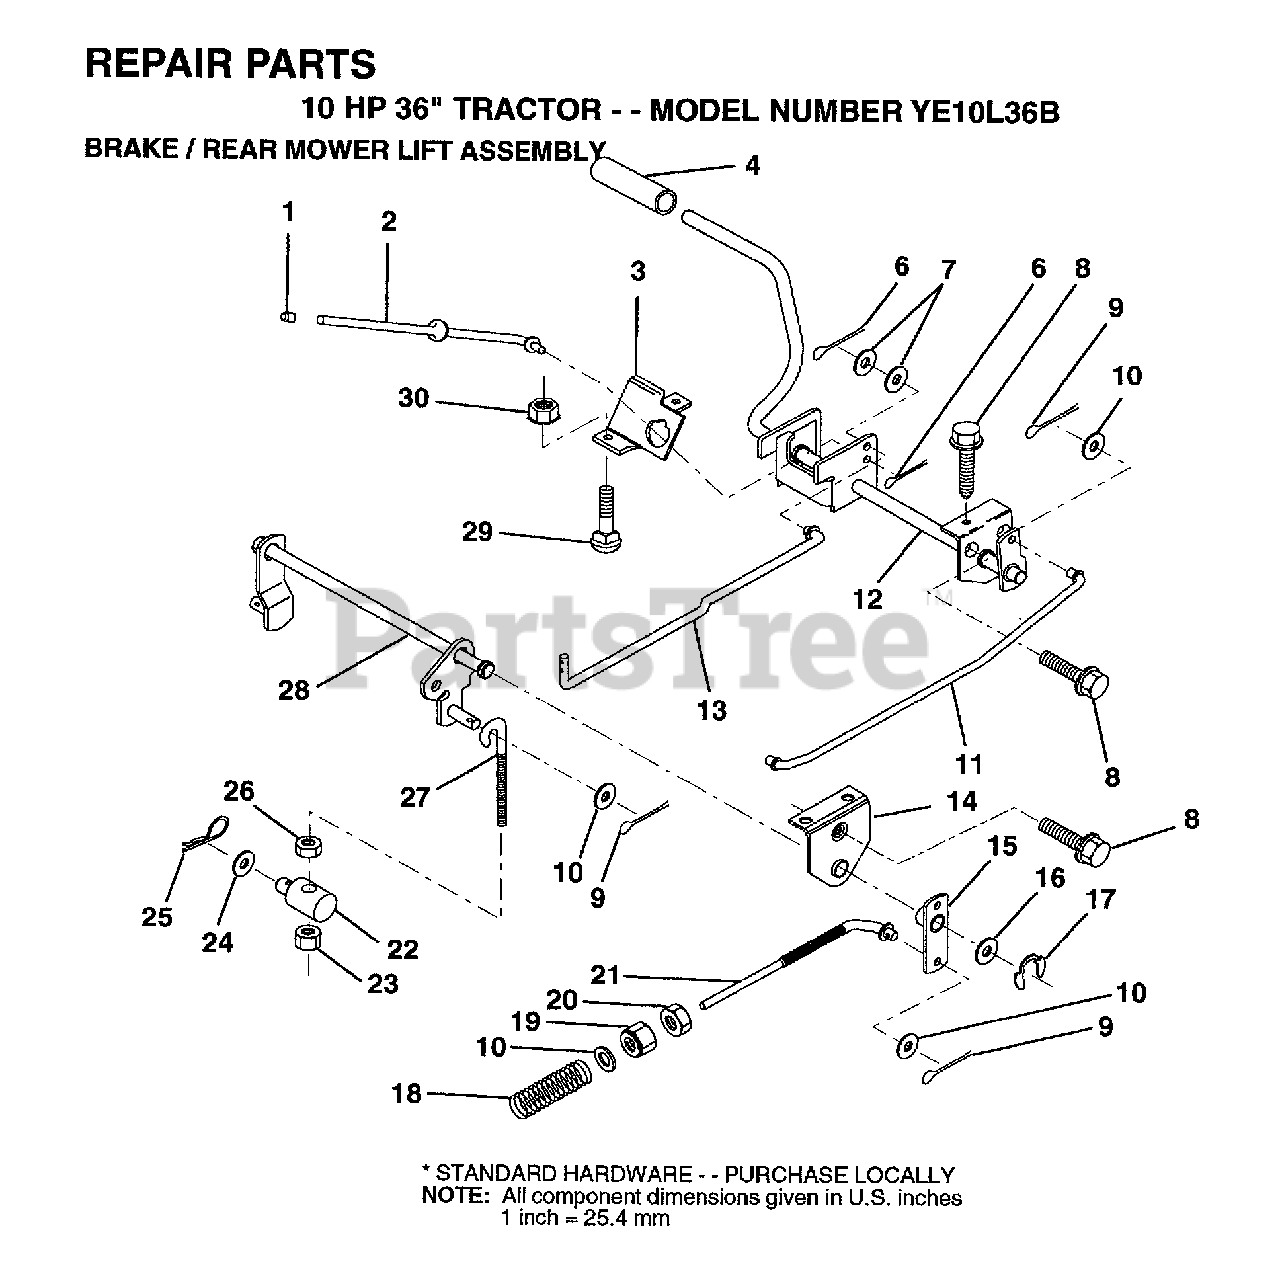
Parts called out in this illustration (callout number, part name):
1	PLUNGER CAP T
2	"ROD,PARK BRAKE"
3	"BRKT,PARK BRAKE"
4	PEDAL COVER T
7	WASHER
8	SCREW LT
9	COTTER PIN
10	WASHER
13	"ROD,CLUTCH"
14	"BRKT,LIFT SHAFT"
15	PVT BRAKE ARM ASM
16	WASHER T
17	KLIP RING
18	SPRING ROD LT
20	NUT
24	WASHER
25	SPRING.RETAINER
26	LOCKNUT
27	"LINK, MOWER REAR"
